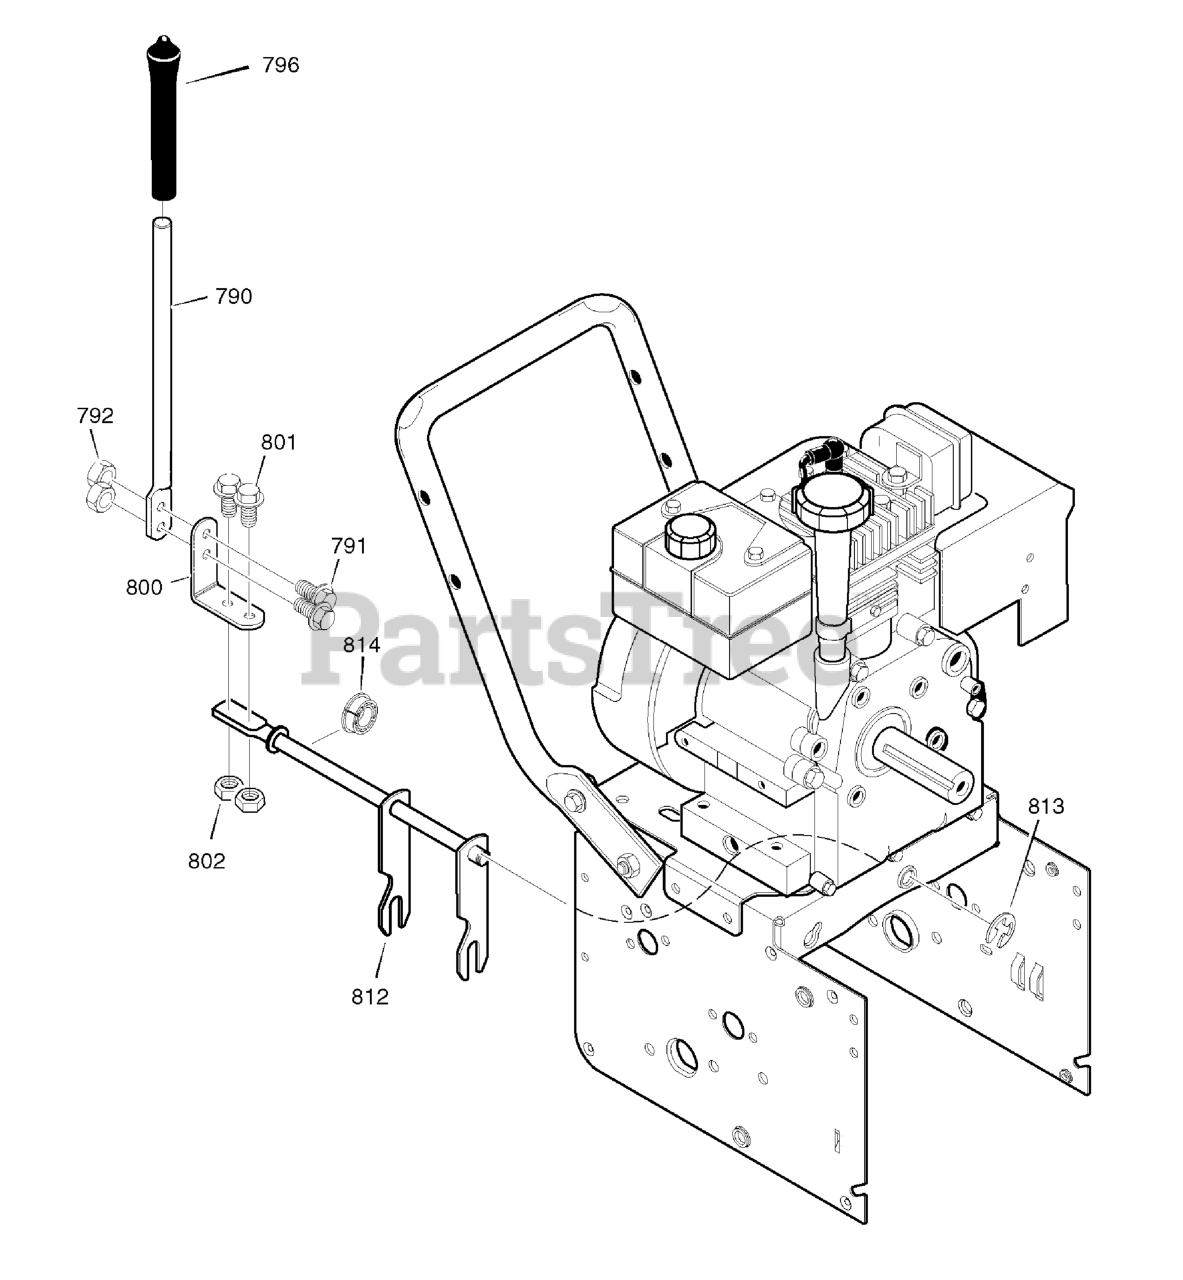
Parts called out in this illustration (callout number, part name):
790	ROD, SHIFT
791	SCREW, 1/4-20 X .75
792	NUT, 1/4-20
796	KNOB, SLIP
800	LEVER, SPRING
801	SCREW, 1/4-20 X .75
802	NUT, 1/4-20
812	ROD ASSEMBLY, SPEED SELECT
813	RETAINER, RING
814	BEARING, FLANGED
